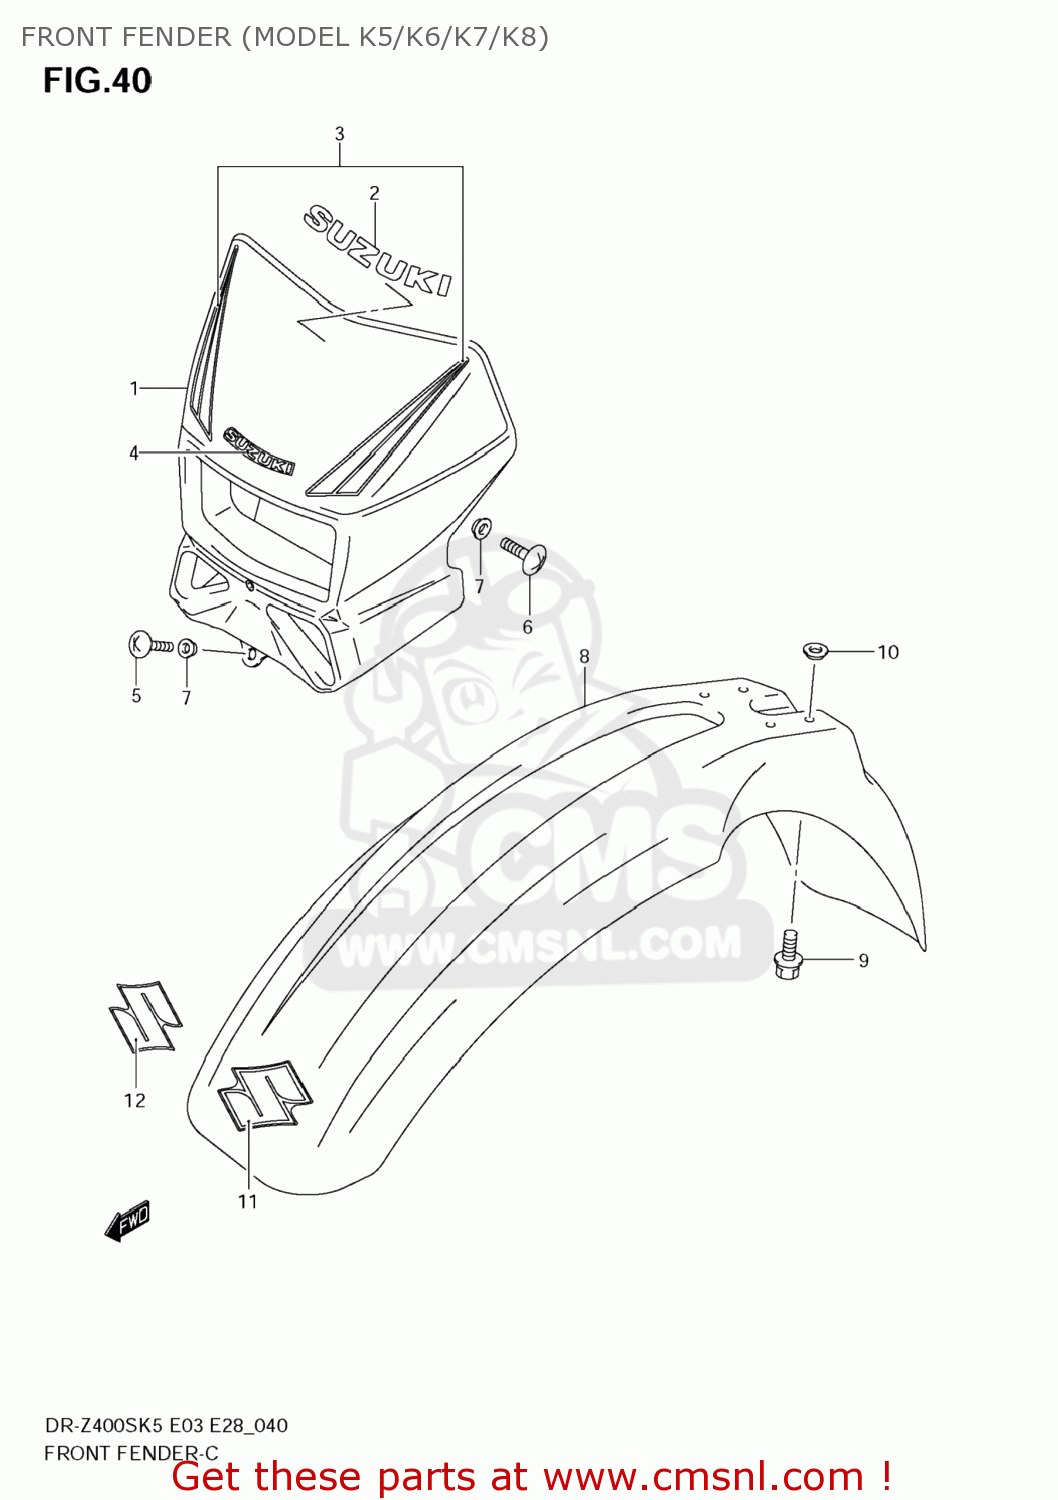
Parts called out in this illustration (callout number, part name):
1	COVER,HEADLAMP
2	TAPE,HEADLAMP HOUSING
3	TAPE SET,HEADLAMP HOUSING
4	EMBLEM,SUZUKI
5	SCREW 5X12
6	SCREW 6X12
7	WASHER
8	FENDER,FR
9	BOLT(6X16)
10	WASHER
11	EMBLEM,S
12	EMBLEM,S
